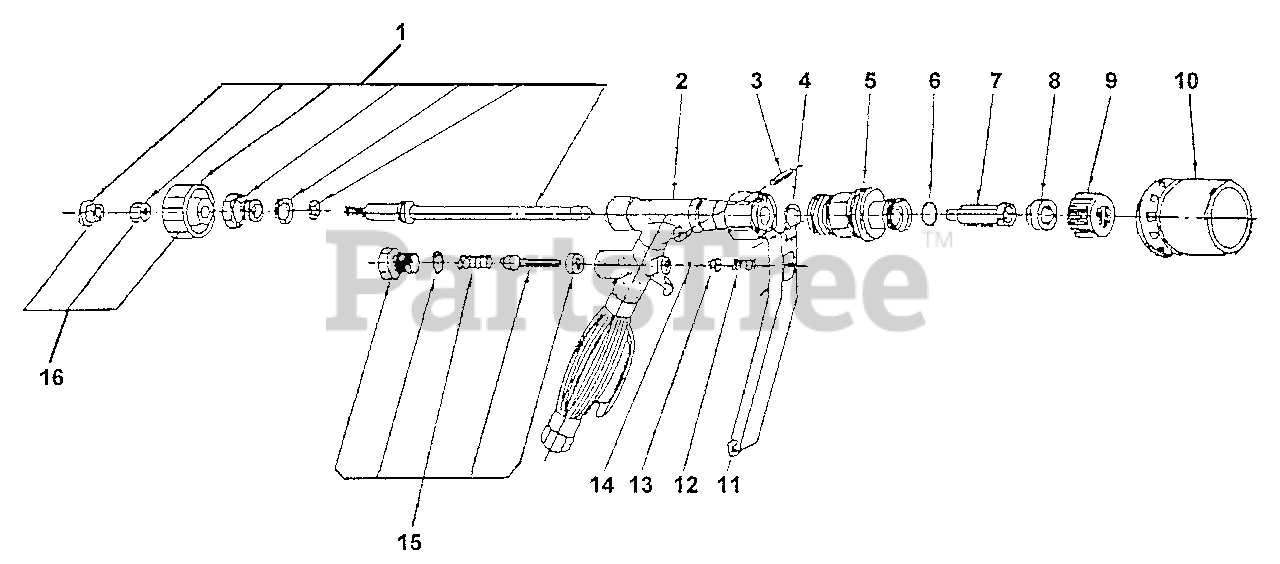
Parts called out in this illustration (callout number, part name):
1	VALVE SHAFT ASSY
2	BODY, GUN
3	PIN - SPRING -- 4X20
4	O-RING - 11
5	HOLDER, VALVE
6	O-RING - 12
7	CORE, ZOOM
8	NOZZLE, PLATE
9	CAP
12	SPRING, LEVER
14	O-RING - 3
15	VALVE SHAFT ASSY
16	KNOB
